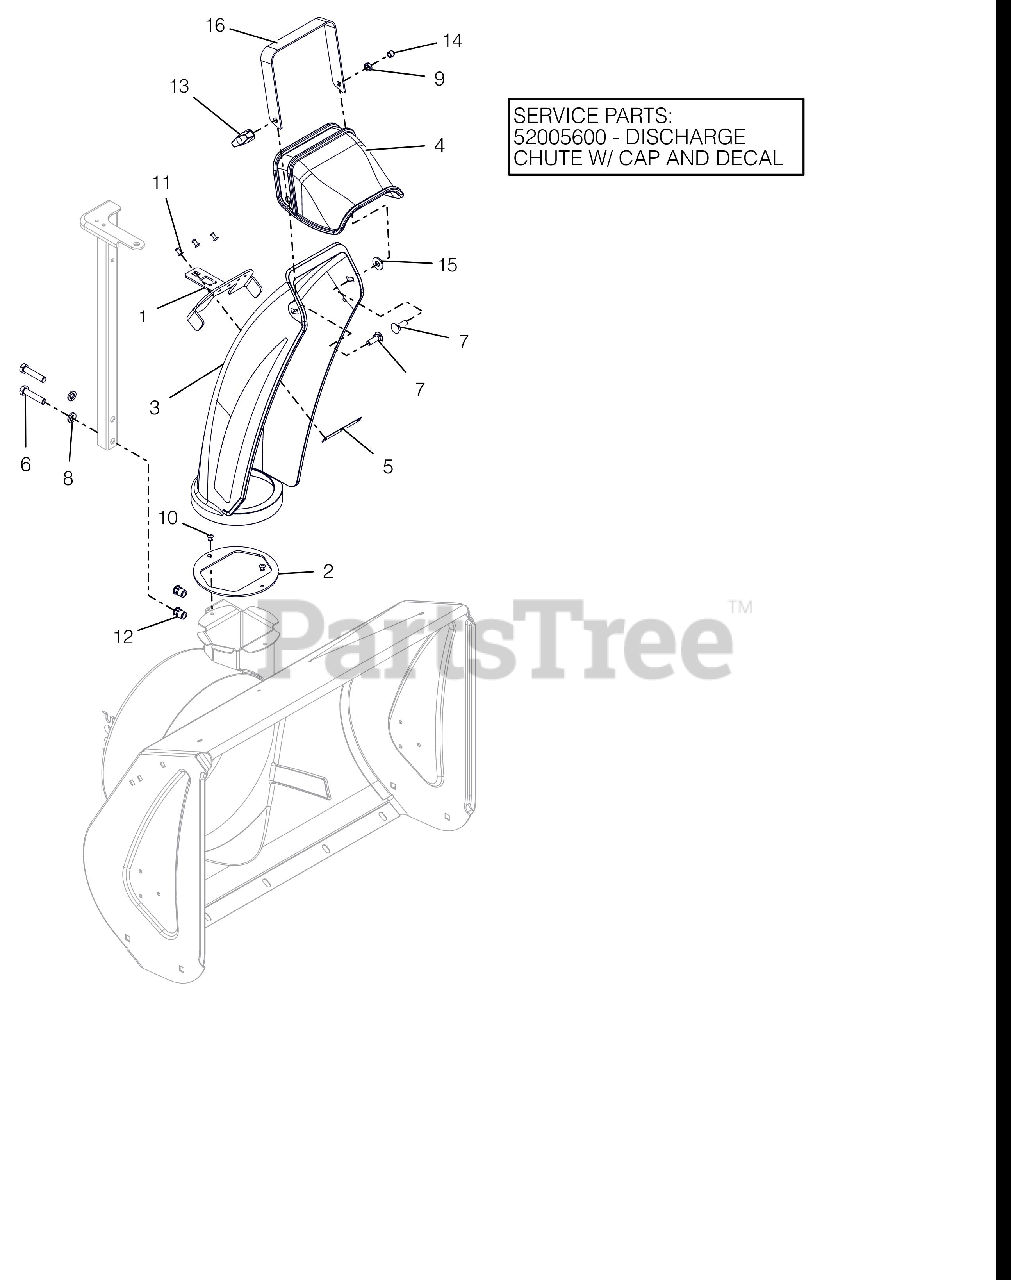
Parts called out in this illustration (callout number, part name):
1	CHUTE MOUNT BRACKET
2	BAFFLE, COMPACT DISCHARGE
3	CHUTE, PLASTIC DISCHARGE LONG
3	CHUTE, MANUAL DISCHARGE W/CAP
4	CAP,PLASTIC - SNOTEK (W/DECAL)
5	PLATE,CHUTE MOUNT BACKING
6	@BLT-HEX .38-16X1.75 GR5 YWZC
7	BLT,RNHDRECSHNK .31-18X1.00
8	@WSHR-LK .38X.094 REG YWZC
9	@NUT-LK-CTR-JAM .31-18 YWZC
10	RVT-POP .187 YZ
11	RIVET, #66 STEEL POP PD BLACK
12	NUT, THREADED INSERT .38-16
13	KNOB, WING .31-18 UNC
14	CAP, END .281X.313
15	@WSHR-FL-STL.38X.875X.083 YWZC
16	HANDLE, MANUAL CHUTE CAP
